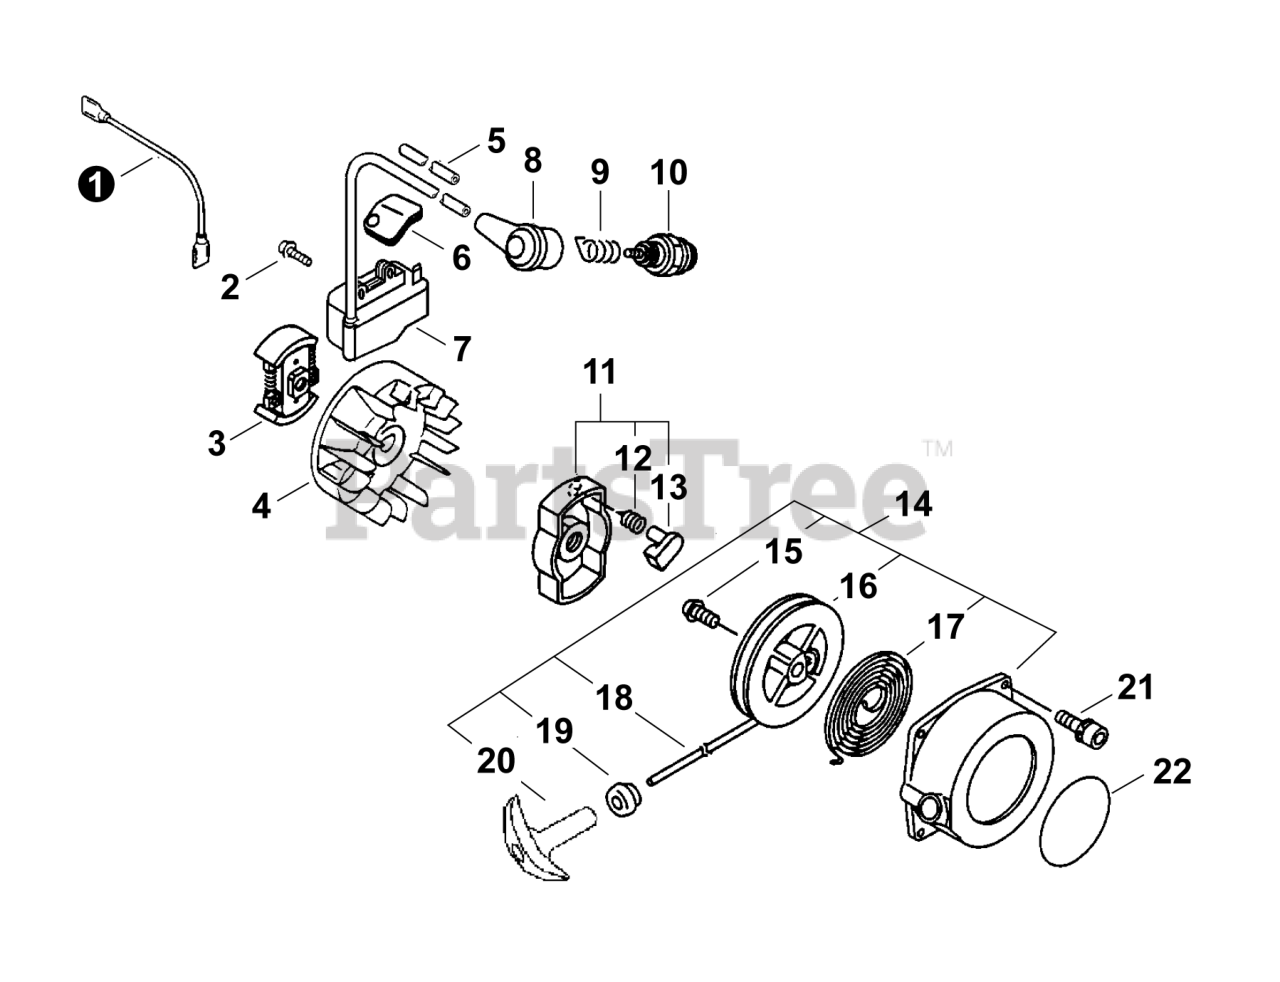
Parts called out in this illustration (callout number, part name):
2	BOLT 4×20
4	FLYWHEEL
5	TUBE, INSULATOR
7	COIL, IGNITION
8	CAP, SPARK PLUG
9	TERMINAL, SPARK PLUG
10	SPARK PLUG - BPM8Y
11	PAWL ASSY, STARTER
12	SPRING, RETURN
13	PAWL, STARTER - BLACK
14	STARTER ASSY, RECOIL
15	GRIP, STARTER
16	REEL, ROPE
17	SPRING, RECOIL
18	ROPE, STARTER
19	GUIDE, ROPE
20	GRIP, STARTER
21	BOLT 4×16
22	LABEL - STARTER - ECHO
